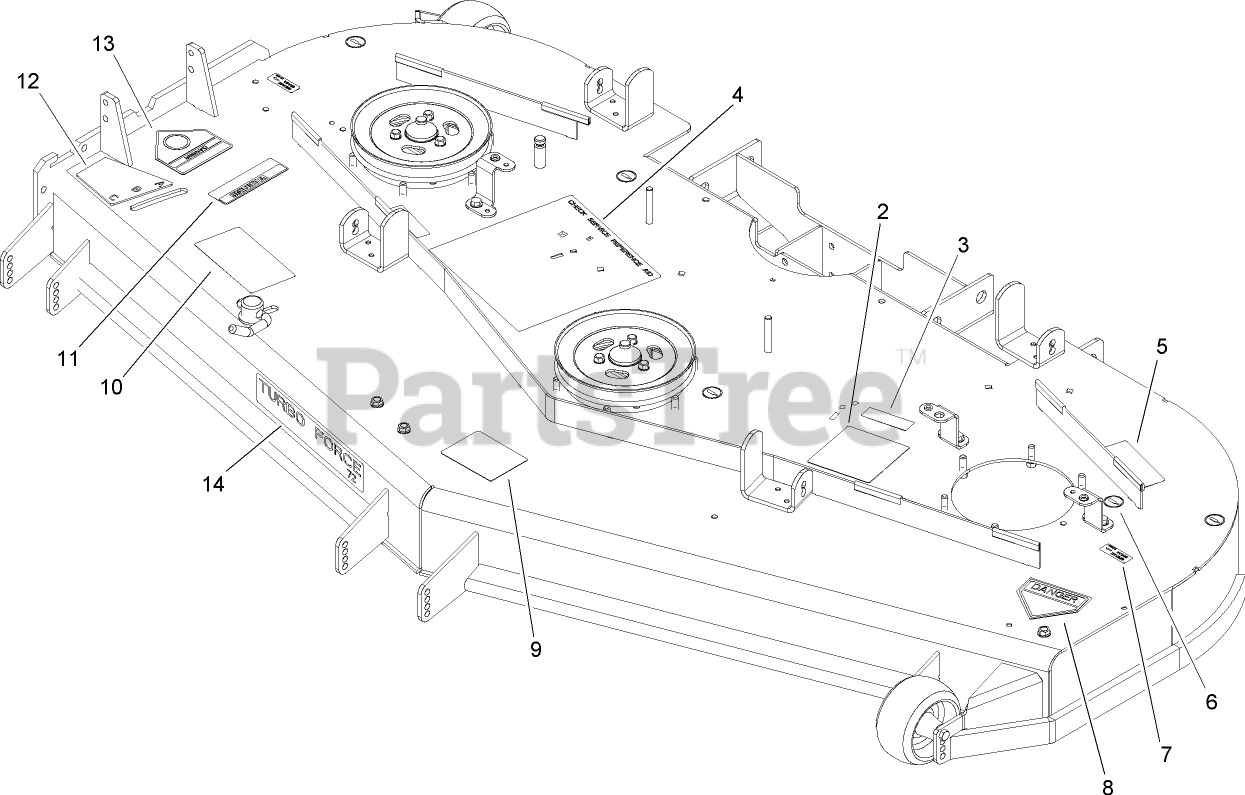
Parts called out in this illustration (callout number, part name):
2	DECAL-ROUTING, BELT
3	DECAL-COVER, MISSING
4	DECAL-CHECK, SERVICE
5	DECAL-TORQUE
6	DECAL-GREASE
7	Decal-Grease
8	DECAL-DANGER
9	DECAL-SCALP, ANTI
10	DECAL-DANGER, THROWN OBJECT
11	DECAL-WARNING
12	DECAL-ADJUSTMENT, BAFFLE
13	DECAL-DANGER
